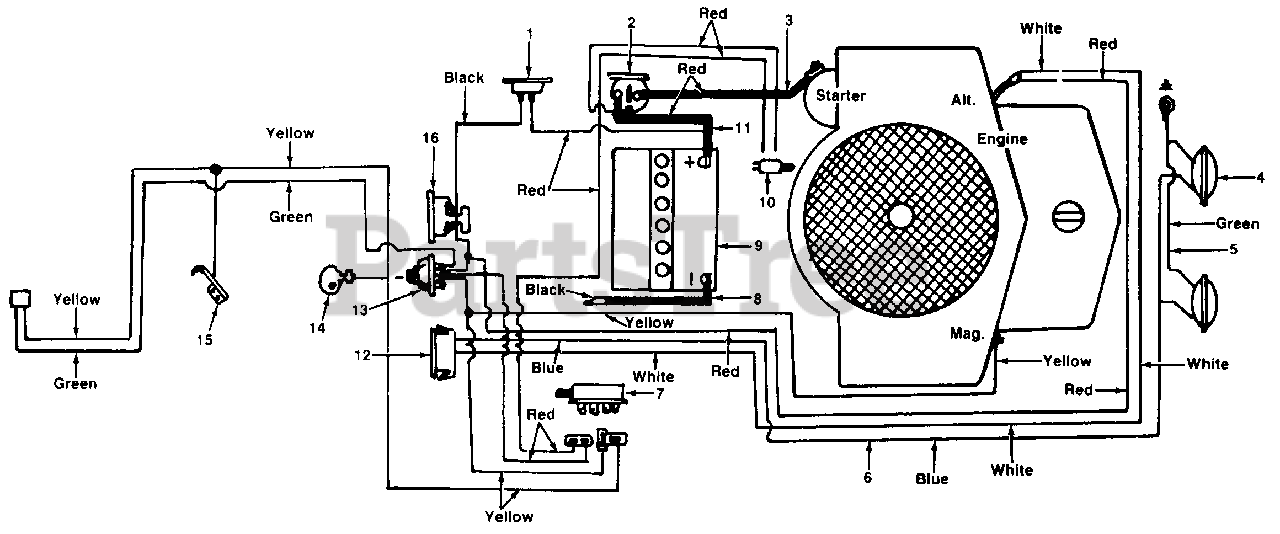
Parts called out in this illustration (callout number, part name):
1	Circuit Breaker
2	Solenoid
4	Headlight
5	Ground Wire
6	Wire Harness
7	Safety Switch
8	6 Ga. Black Wire
9	32V Battery
10	Safety Switch
11	Wire
12	Light Switch
13	Ignition Switch
14	Ignition Key
15	Spring Switch
16	Ammeter
